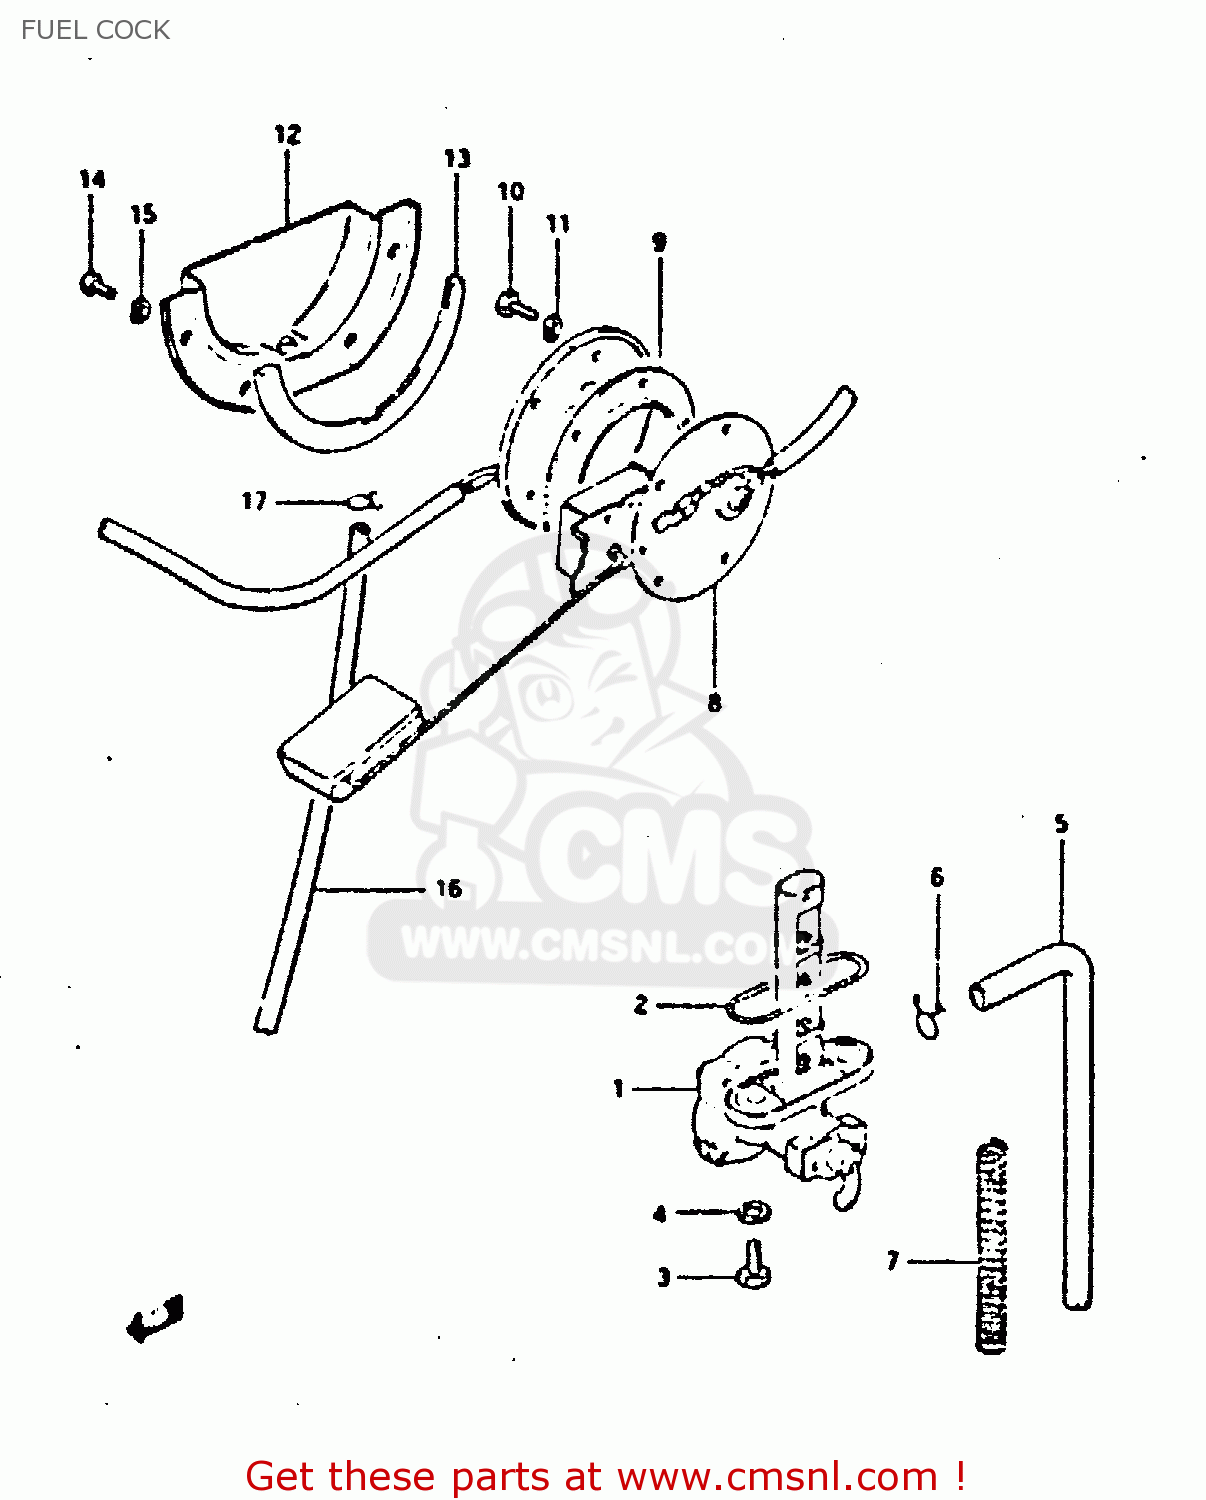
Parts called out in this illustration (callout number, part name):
1	COCK ASSEMBLY,FUEL
2	O RING
3	BOLT(6X20)
4	GASKET
5	HOSE
6	CLIP
7	SPRING
8	GAUGE ASSEMBLY,FUEL LEVEL
9	GASKET,FUEL LEVEL GAUGE (NAS)
10	BOLT 5X10
11	LOCK WASHER
12	PLATE,FUEL DRAIN
13	GASKET (NAS)
14	SCREW
15	LOCK WASHER
16	HOSE,FUEL
17	CLIP
